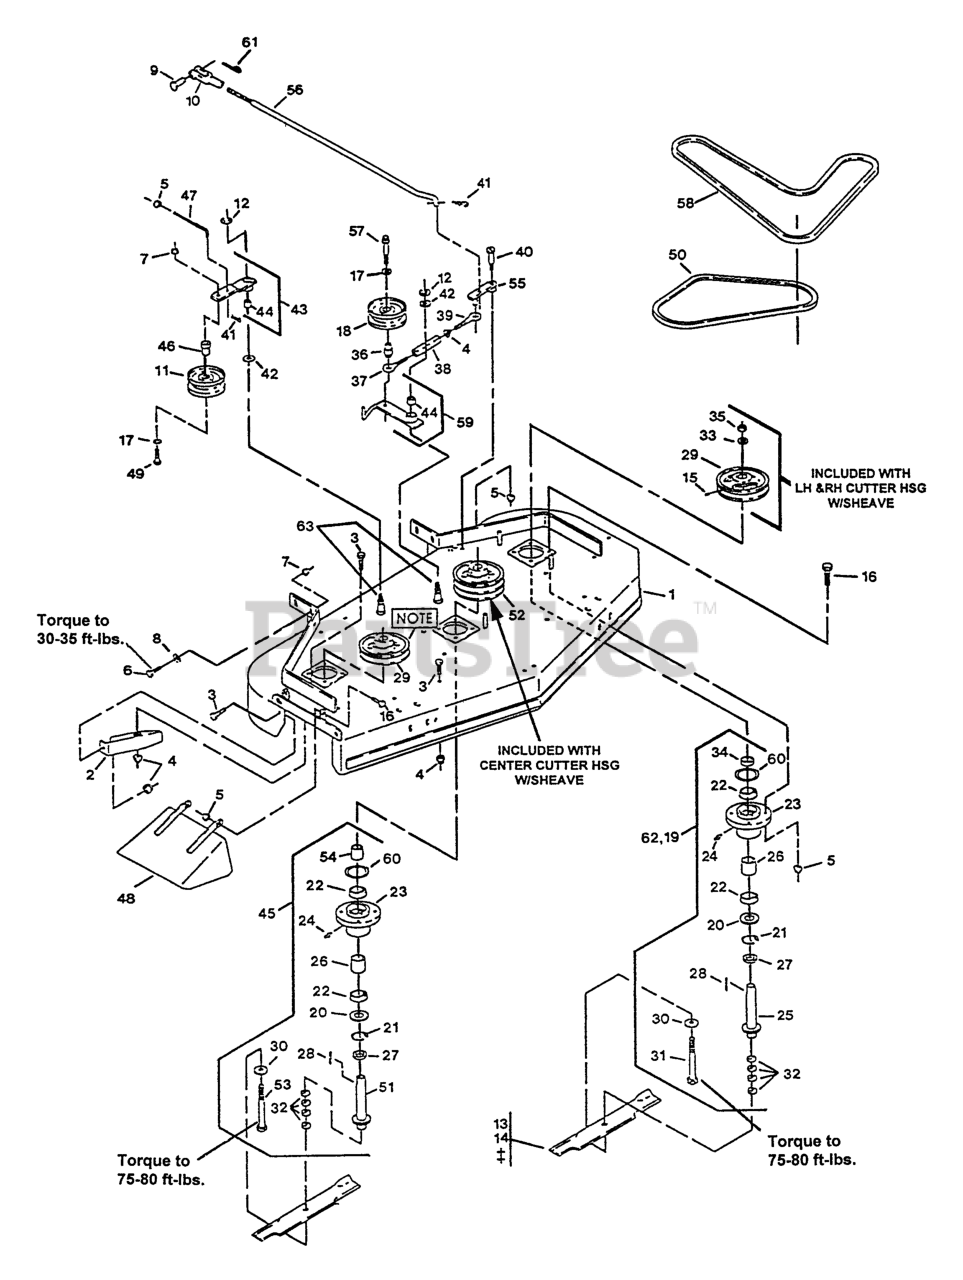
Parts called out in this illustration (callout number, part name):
2	BAFFLE-DOGLEG
9	PIN-CLEVIS
10	YOKE-ADJUSTABLE
11	IDLER,PULLEY
15	SCREW-SET
19	ASM,HOUSING CUTTER
20	SEAL,DUST
21	RING,SNAP WLDS N5000-244
22	BEARING,HD SPINDLE
23	HOUSING,CUTTER
26	SPACER,BRG/BRG
27	SPACER,BEARING &SPINDLE
30	WASHER-SPRING
31	SCREW-CAP, HH
33	WASHER-RETAINER, SHEAVE
36	BUSHING-ENGAGEMENT
37	EYEBOLT-THREAD, LH
38	BODY-TURNBUCKLE
39	EYEBOLT-THREAD, RH
40	BOLT,SHLDR KSKH
41	PIN-COTTER
42	WASHER-SPINDLE
43	ARM WLDMNT W/BUSHING
44	BEARING,POWDERED METAL
46	BUSHING-IDLER
47	LINKAGE
48	Chute
50	BELT,FRONT DECK
53	SCRW,CAP HH 5/8-18X8.5
54	SPACER,BEARING/SHEAVE
56	ARM-LINKAGE, ASSIST
58	BELT,BLADE DRIVE 36
